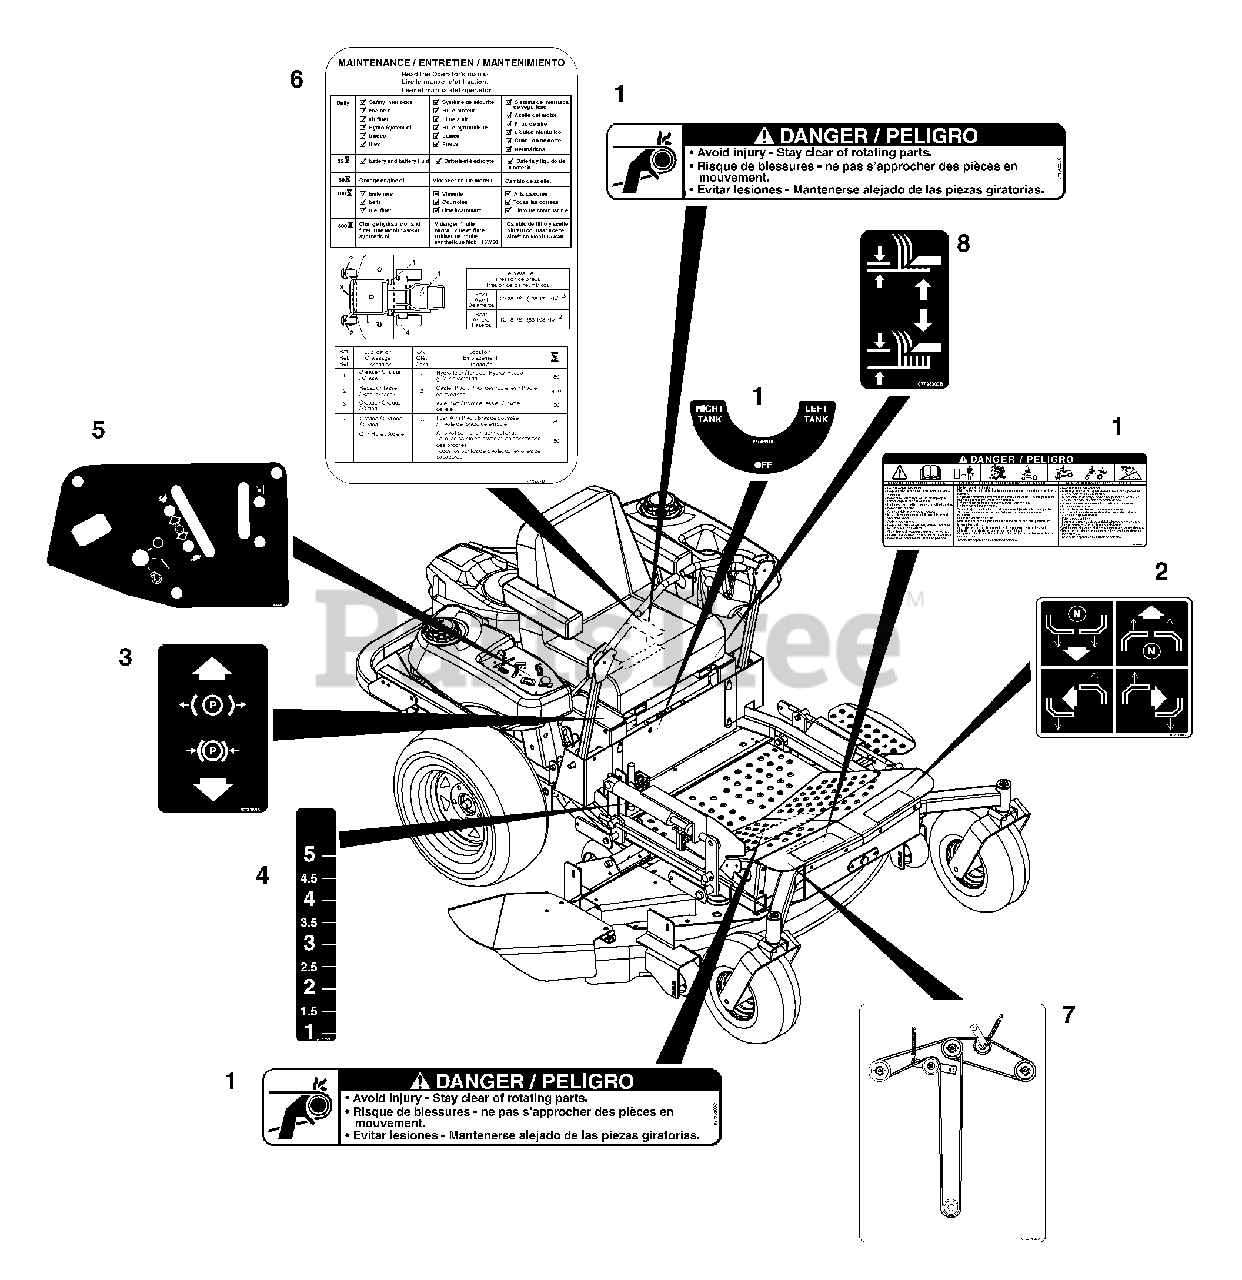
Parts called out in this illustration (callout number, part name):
1	Decal, Set-Common Danger/Fuel
2	Decal-Instructional
3	Decal-Parking Brake Lever
4	Decal, Height of Cut
5	Decal, Control Panel
6	Decal- Service Instructions
7	Decal, Belt Diagram
8	Decal- Lift Lever
